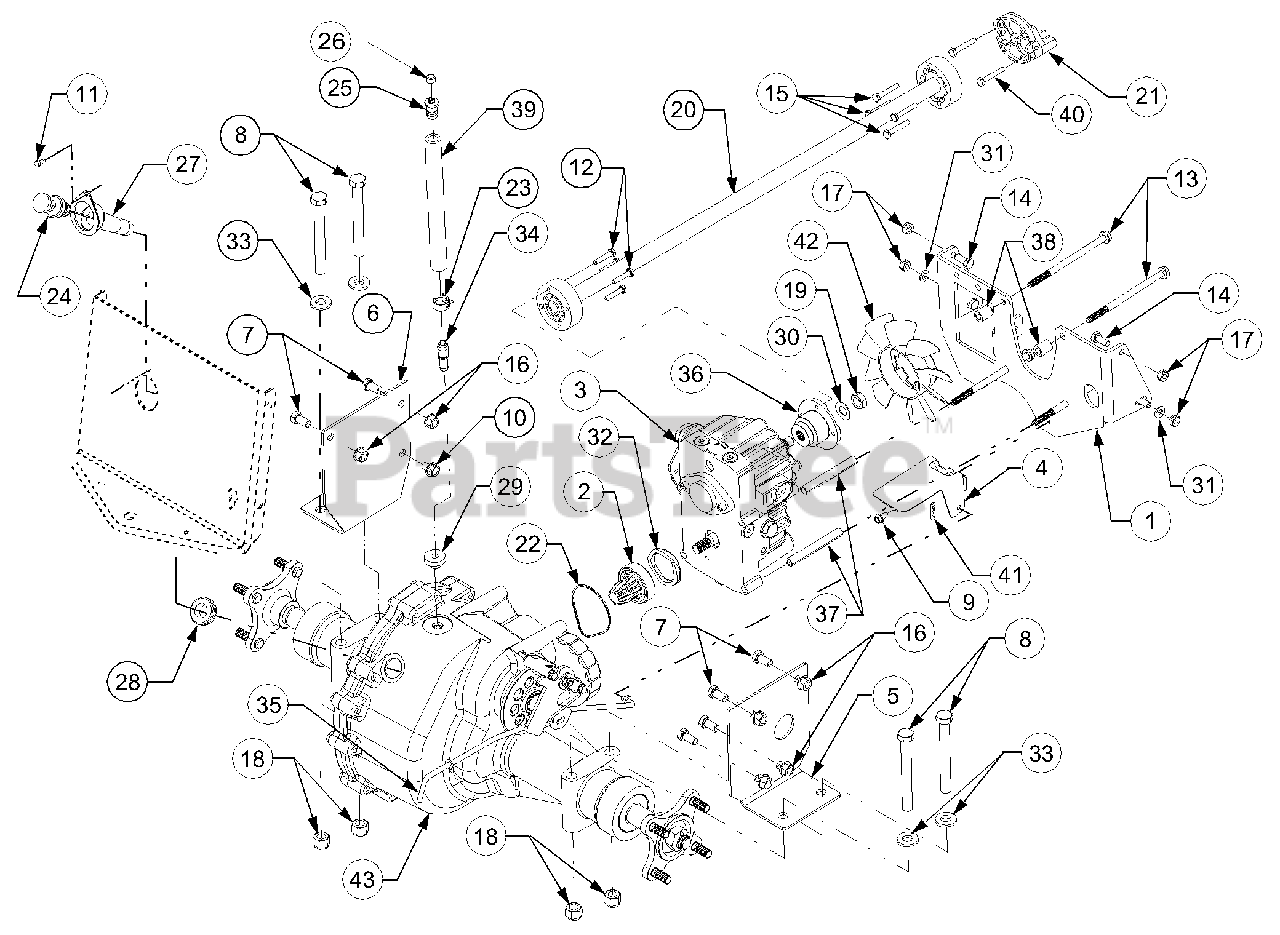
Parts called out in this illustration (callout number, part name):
1	Bracket, Torque
2	Gear Assembly, Pinion
3	Transmission, Hydrostatic
5	Plate, RH Transmission Flange
6	Plate, LH Transmission Flange
7	Scrw, Hx Cap, 3/8-16 x .75 GR5
8	Scrw, Hx Cap, 1/2-20 x 4.5 GR5
9	Scrw, Hx Wsh Hd Tap, 1/4-20 x .5
10	Scrw, Hx Wsh Hd Tap, 3/8-16 x .5
11	Scrw, Hx Wsh Hd Tap, 10-16 x .44
12	Scrw, Hx Lock, 1/4-20 x 1.25 GR5
13	Scrw, Hx Hd Tapp, 5/16-18 x 5.25
14	Scrw, Hx Cap, 5/16-18 x .75 GR5
15	Scrw, Hx Lock, 1/4-20 x 1.62 GR5
16	Nut, Hex Flange Lock, 3/8-16
17	Nut, Hx Cntr Lock, 3/8-16
18	Nut, Hx Nylon Lock, 1/2-20 GR2
19	Nut, Hex Top Lock Jam, 1/2-20
20	Shaft, Drive, 30.875 Lg
21	Adapter, Engine
22	Seal, Gland
23	Clamp, Hose
24	Dipstick, Transmission
25	Vent, Plastic
26	Cap, Plastic Vent
27	Holder, Dipstick
28	Grommet, Rubber, .75 x 1.063
29	Grommet, Rubber, .362 x .56
30	Washer, Belleville
31	Washer, Flat, .344 x .688 x .065
32	Washer, Spring
33	Washer, Flat, .531 x 1.062 x .134
34	Fitting, Tube
35	Rod, Hydro Dump Valve
36	Adapter, Hydro Pump
37	Spacer, Hydro, .323 x .443 3.51
38	Spacer, Hydro, .323 x .600 x .74
39	Tube, Transmission Breather
40	Screw, Hex Cap
41	Internal Cotter Pin
42	Fan, Pump
43	Transmission Assembly, Hydro See "Hydro Transmission" illustration and part list for Parts Info.
